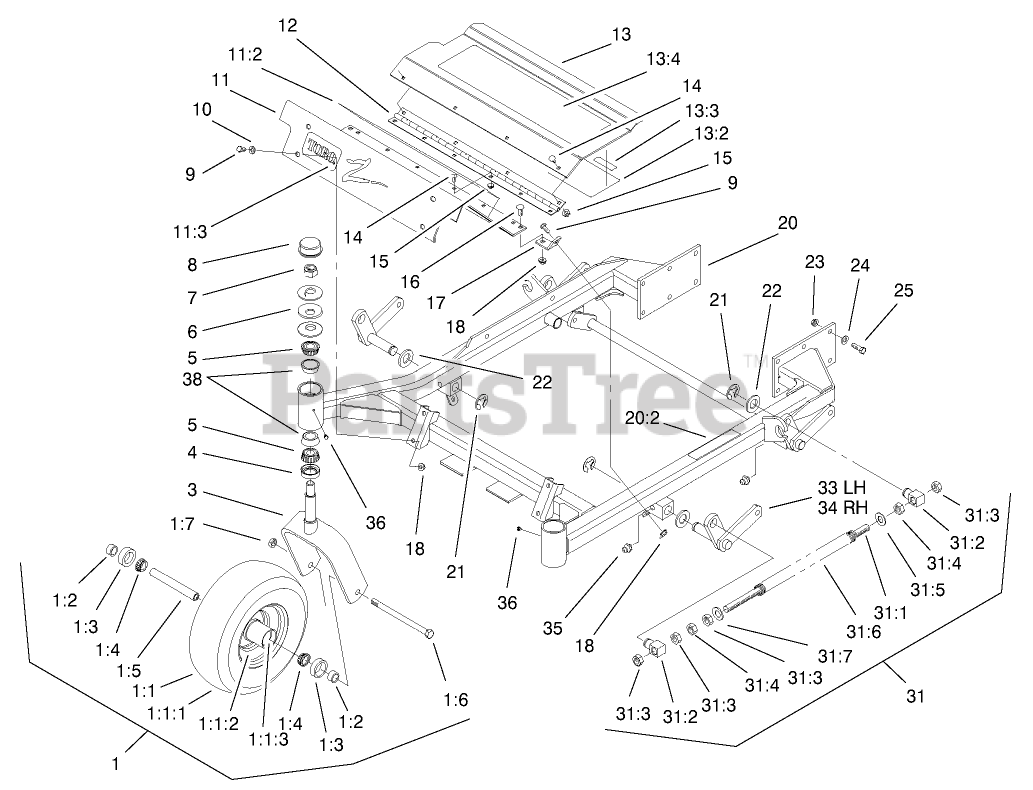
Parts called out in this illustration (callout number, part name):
1	CASTER WHEEL ASM
1:1	WHEEL and TIRE ASM
1:1:3	BEARING-CUP
1:2	SPACER-BEARING
1:3	SEAL-BEARING
1:4	BEARING-CONE, TAPER
1:5	SPACER-CASTER, FRONT
1:6	SCREW-HH
1:7	NUT-LOCK, NI
3	CASTER
4	SEAL-GREASE
5	BEARING-CONE, TAPERED
6	WASHER-BELLVILLE
7	NUT-LOCK, NI
8	CAP-GREASE
9	SCREW-HH
10	WASHER-PLAIN
11	FLOORPAN-FRONT
11:2	PAD-ANTISKID
12	HINGE-FLOORPAN
13	FOOTREST ASM
13:2	DECAL-SERVICE
13:3	DECAL-WARNING
13:4	PAD-ANTISKID
14	SCREW-CARR
15	NUT-HF
16	BOLT-CARR
17	BRACKET-FLOORPAN
18	NUT-HF
20	FRONT FRAME ASM
20:2	DECAL-WARNING
21	RING-RETAINING, EXT
22	WASHER-FLAT
23	NUT-HHF, WHIZ
24	WASHER-BELLEVILLE
25	SCREW-HH
31	Front Spring ASM
31:1	ROD-LIFT, DECK
31:2	SWIVEL-DECK MOUNT, REAR
31:3	NUT-HEX
31:4	NUT-JAM
31:5	Washer
31:6	SPRING-COMPRESSION
31:7	WASHER-FLAT
33	LH LIFT ARM ASM
34	RH LIFT ARM ASM
35	FITTING-GREASE
38	BEARING-CUP, TAPERED
